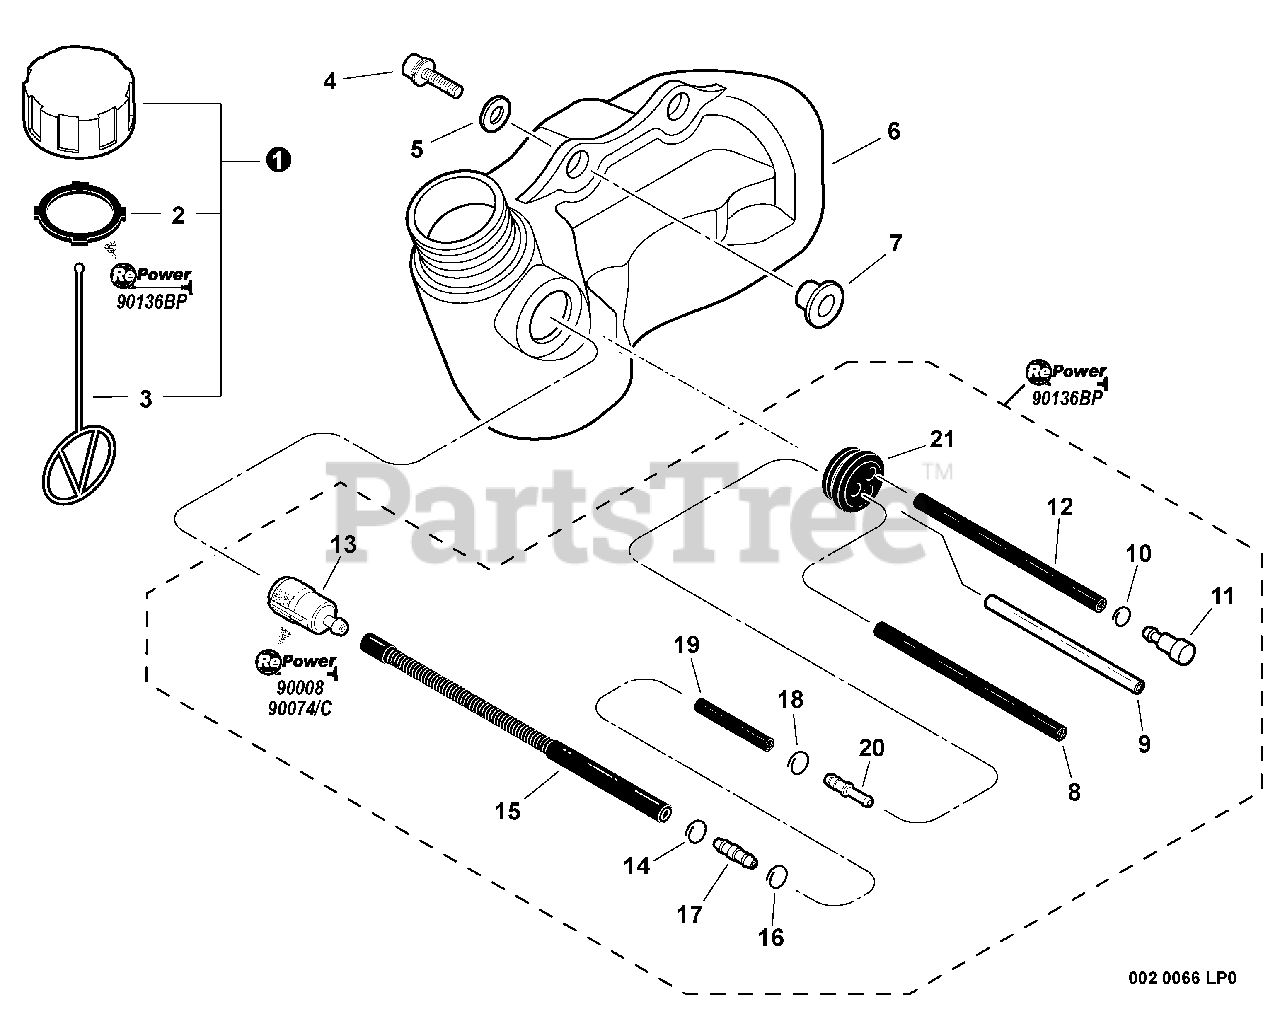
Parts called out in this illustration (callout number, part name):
1	CAP ASSY - ORANGE
2	GASKET, CAP
3	CONNECTOR, CAP
4	SCREW - 5X20
5	WASHER - 5
6	TANK, FUEL
7	COLLAR - 5
8	PIPE - 3X5X61 -- BLACK
9	PIPE - 3X6X75 -- CLEAR
10	CLIP - 6
11	VENT, FUEL TANK
12	PIPE - 3X6X50 -- BLACK
13	FILTER, FUEL
14	CLIP - 6.6
15	PIPE, FUEL - CORRUGATED
16	CLIP - 6.5
17	CONNECTOR, PIPE
18	CLIP - 6.5
19	PIPE - 3X6X35 -- BLACK
20	CONNECTOR, PIPE
21	GROMMET
22	RePower FILTER KIT
23	RePower TUNE-UP KIT
24	RePower FUEL SYSTEM KIT
